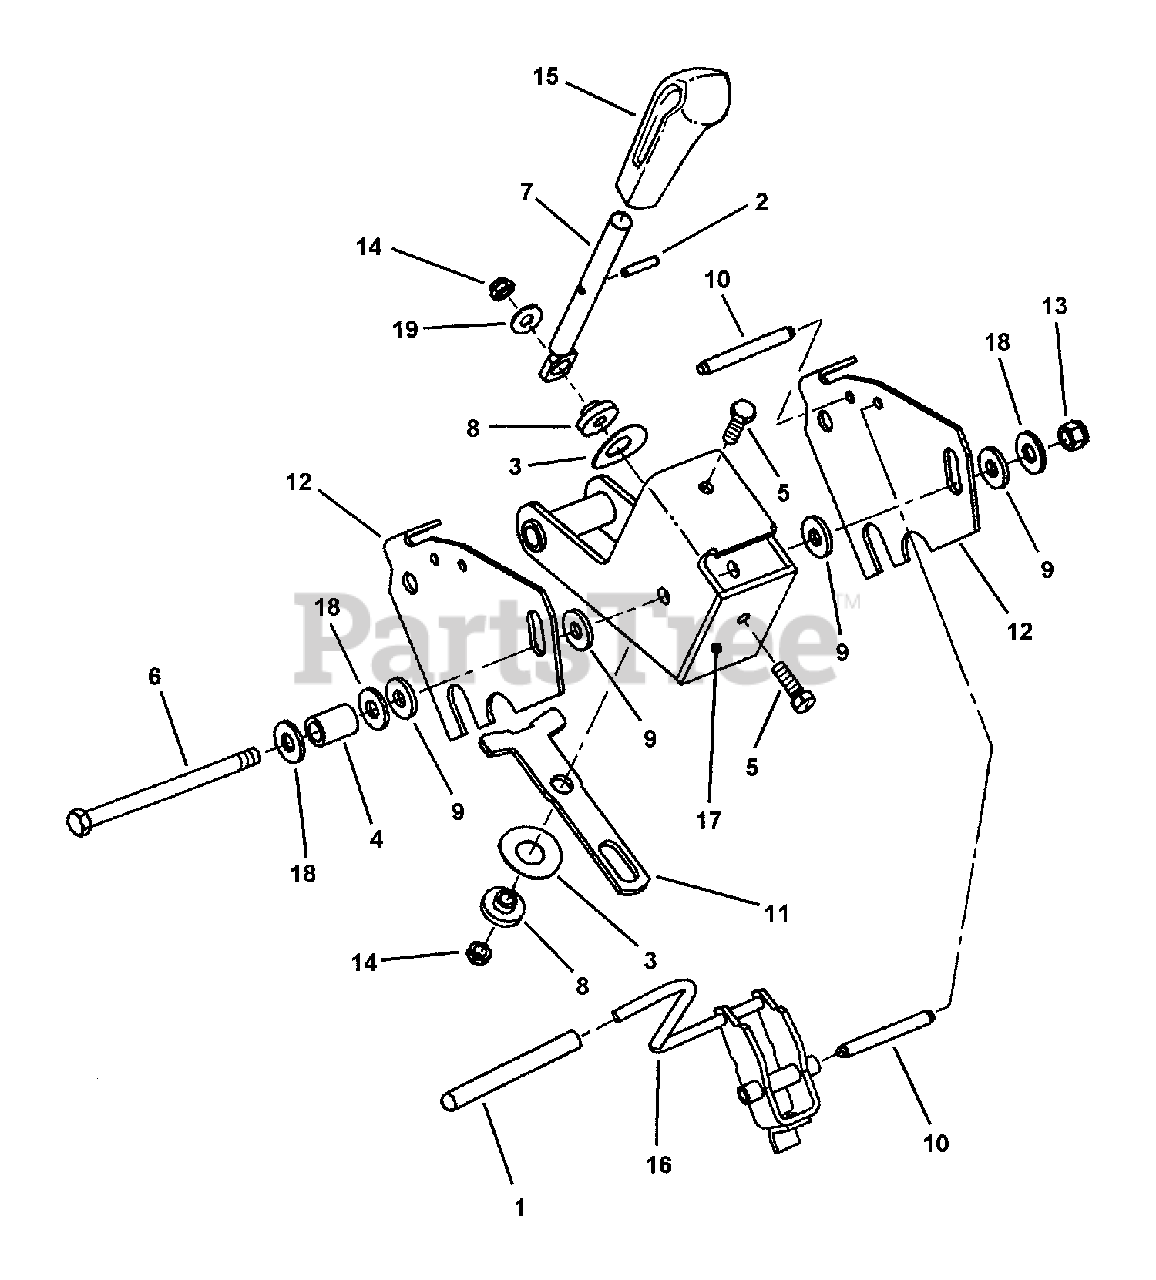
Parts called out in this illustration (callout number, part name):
1	GRIP, Vinyl
2	PIN, 3/16 x 1" Roll
3	WASHER, 5/8" I.D., 1-1/4" O.D. Belleville
4	SPRING, Compression
5	BOLT, 5/16-18 X 1 GD5 YZ
6	BOLT, 3/8-16 X 5" GD5 YZ
7	LEVER
8	BUSHING
9	WASHER, Slipper
10	PIN, Shoulder
11	CAM, Track
12	PLATE, Speed, Accutrack
13	NUT, 3/8-16 HEX NYLON LOCK
14	NUT, 5/16-18 Hex Top Lock, GR B
15	HANDLE, Shift Lever
16	WELDMENT, Neutral Latch
17	TRACK, Welded
18	WASHER, .44 x 1.0 x .08 Flat
19	WASHER, .33 x .88 x .09 Flat
